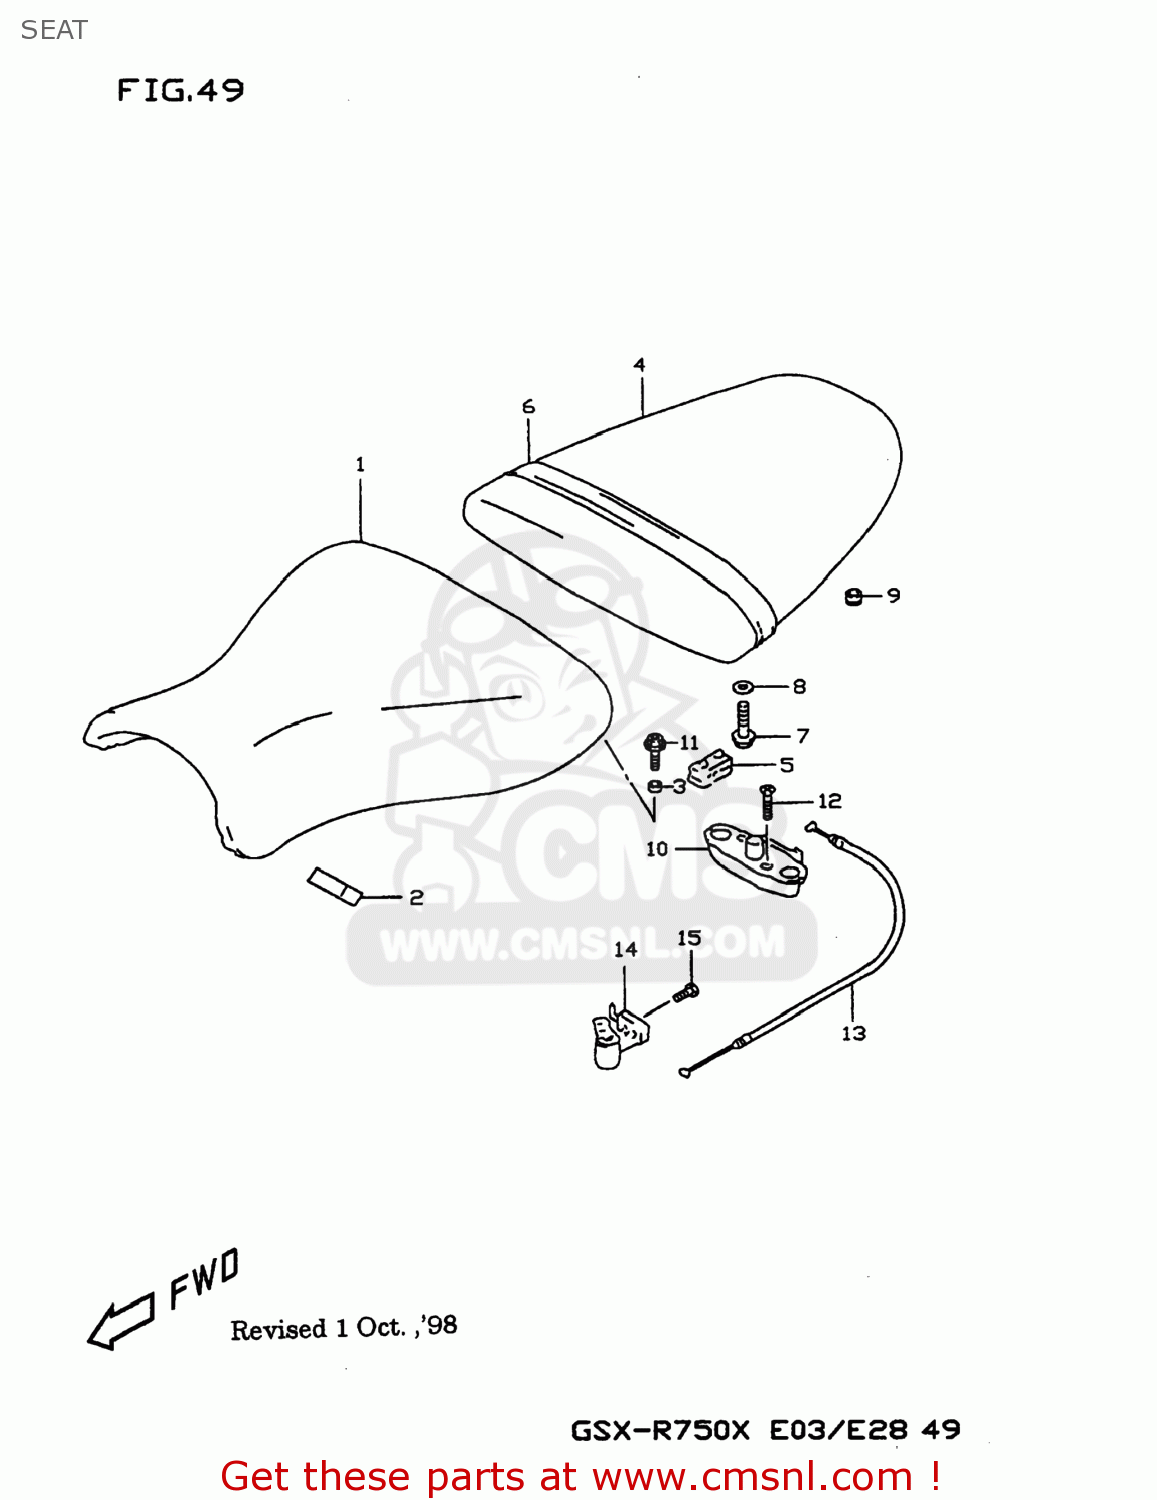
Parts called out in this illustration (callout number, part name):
1	SEAT ASSY(BLACK)
2	CUSHION,FR(20X40X15)
3	SPACER,SEAT(6.5X10.5X6)
4	SEAT ASSY,PILLION
5	CUSHION,SEAT(40X20X15)
6	BAND,SEAT
7	BOLT
8	WASHER(6.5X20X1.6)
9	CUSHION
10	BRACKET,SEAT SUPPORT,RIGHT
11	BOLT(6X18)
12	SCREW
13	CABLE,SEAT LOCK
14	LOCK SET,SEAT
15	SCREW
